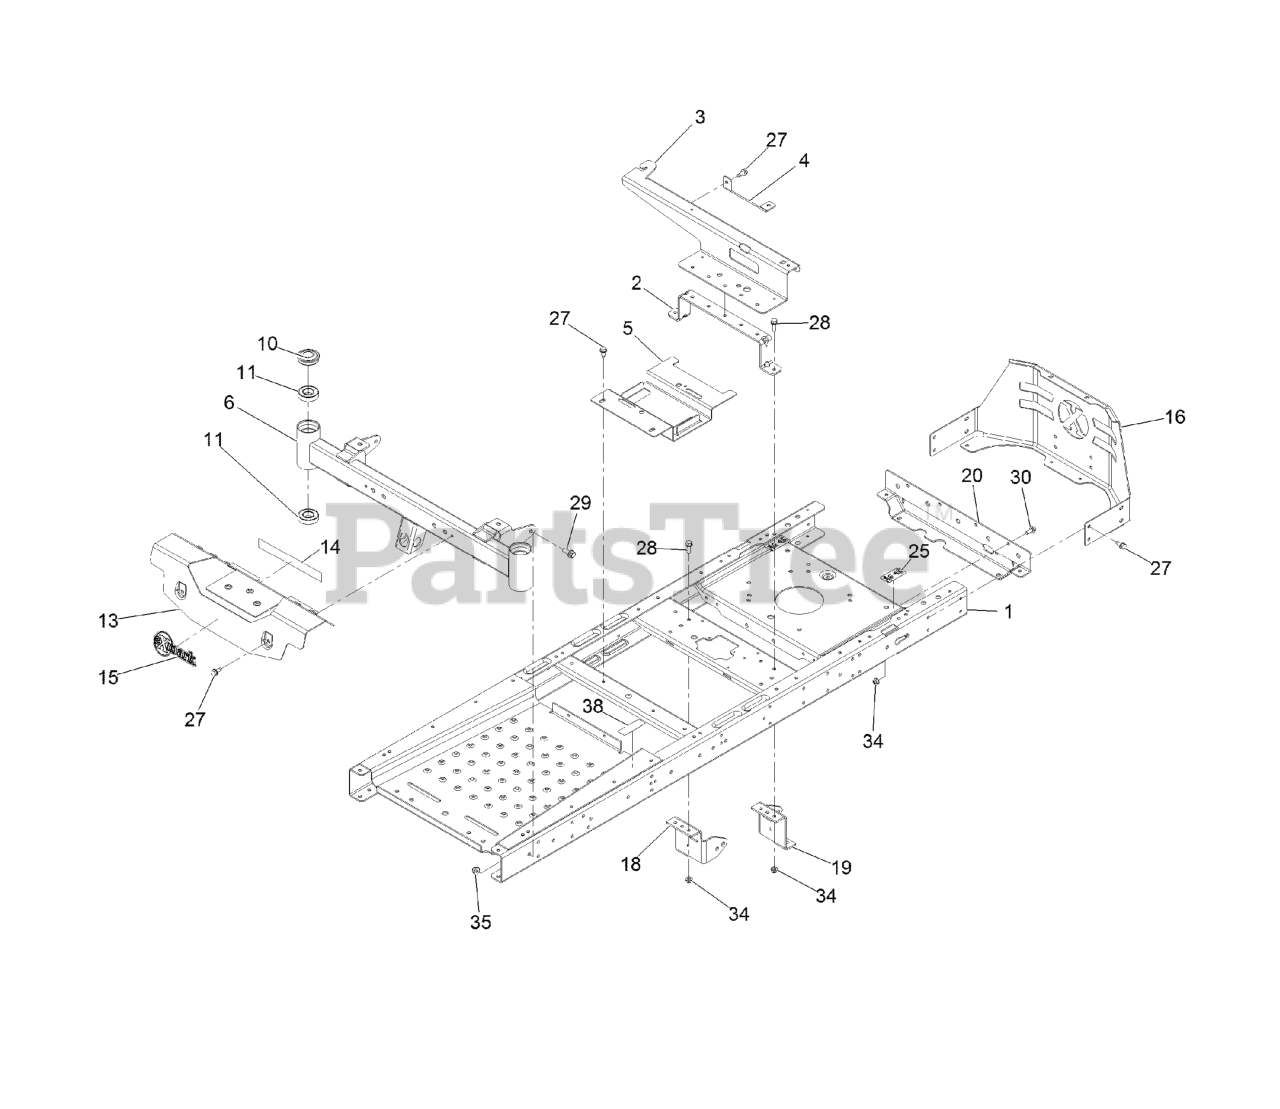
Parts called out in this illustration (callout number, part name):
1	FRAME ASM
2	BRACE-SEAT, REAR (NARROW)
3	SUPPORT-POD
4	SUPPORT-TANK, REAR
5	BRACKET-BATTERY
6	AXLE-FRONT, NARROW
10	CAP-GREASE
11	BEARING-BALL
13	FOOTREST ASM
14	DECAL-WARNING
15	DECAL-EXMARK LOGO
16	GUARD-ENGINE, NARROW
18	MOUNT-HYDRO, FRONT (RIGHT
19	MOUNT-HYDRO, FRONT (LEFT)
20	CROSSMEMBER-REAR, NARROW
25	DECAL-BYPASS
27	Screw-HWH 5/16-18 X 3/4 Tf
28	SCREW-HHF
29	SCREW-HHF 3/8-16 X 1
30	SCREW-HHF
34	NUT-HF, NI
35	NUT-HF, NI
38	DECAL-BRAKE, PARKING
